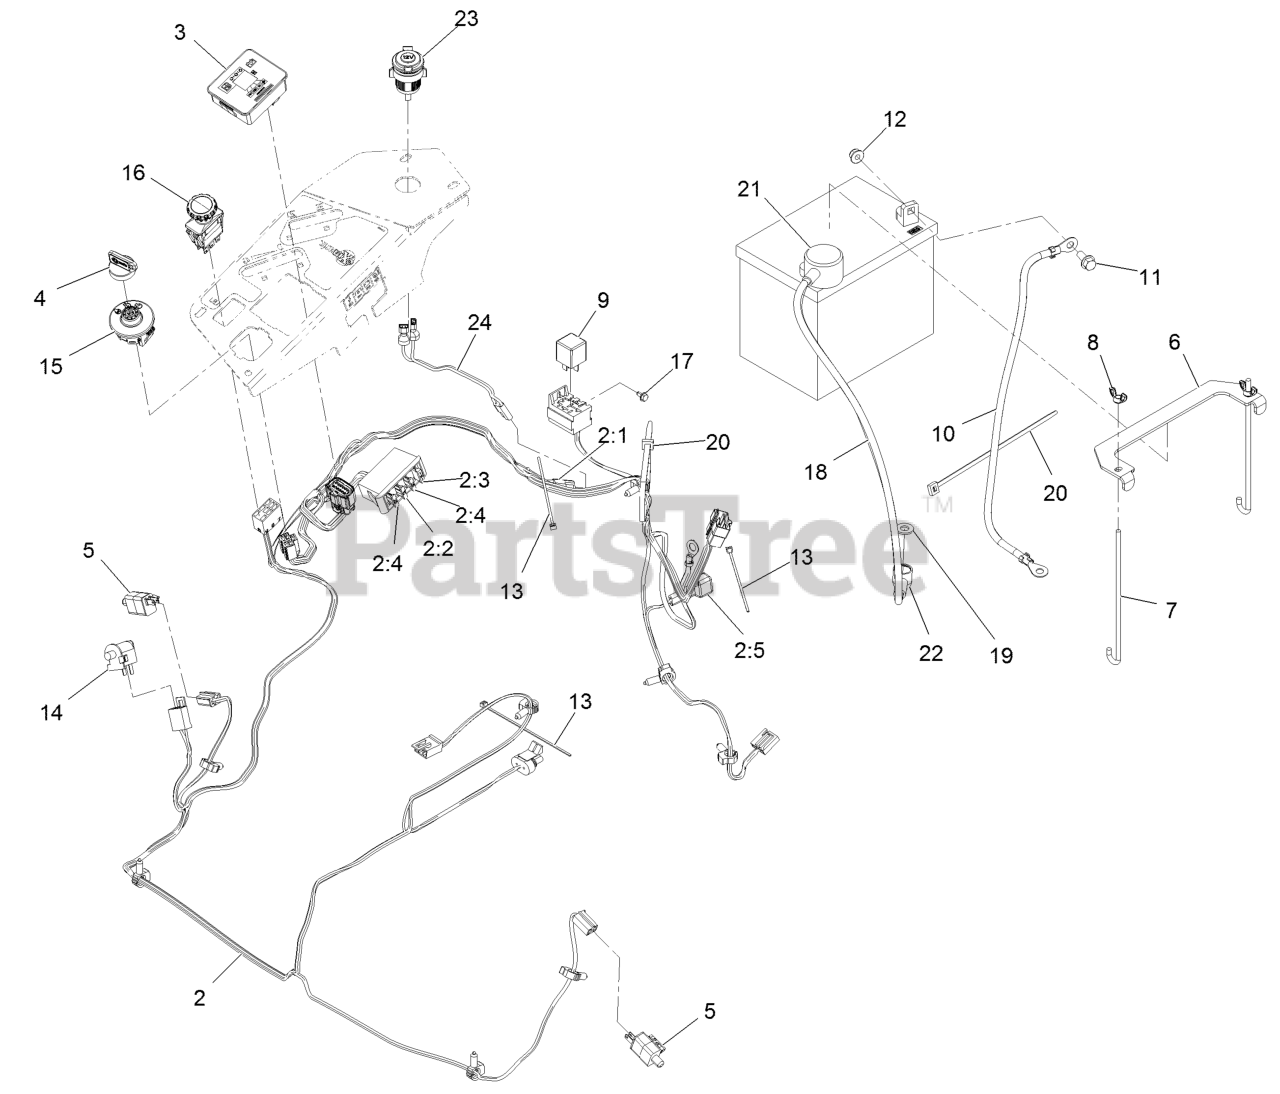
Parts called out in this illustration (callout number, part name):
2	HARNESS-WIRE, MAIN
2:2	FUSE-BLADE, 10 AMP
2:3	FUSE-BLADE, 15 AMP
2:4	FUSE-BLADE, 25 AMP
2:5	CAP-PLUG
3	FUEL/HOUR METER ASM
4	KEYS-IGNITION (SPARE PAIR
4	KEY-IGNITION
6	STRAP-TIE DOWN, BATTERY
7	BOLT-HOLDDOWN
8	WINGNUT
10	CABLE-BATTERY, NEGATIVE
11	SCREW-HHF
12	NUT-HF, NI
13	TIE-CABLE
14	SWITCH-BAIL
16	SWITCH-PTO, 10 AMP
17	SCREW-HWH
18	CABLE-BATTERY, POSITIVE
19	WASHER-FLAT
20	TIE-PLASTIC
21	INSULATOR-BATTERY
22	INSULATOR-SOLENOID
23	RECEPTACLE-12V
24	HARNESS, RECEPTACLE 12V
